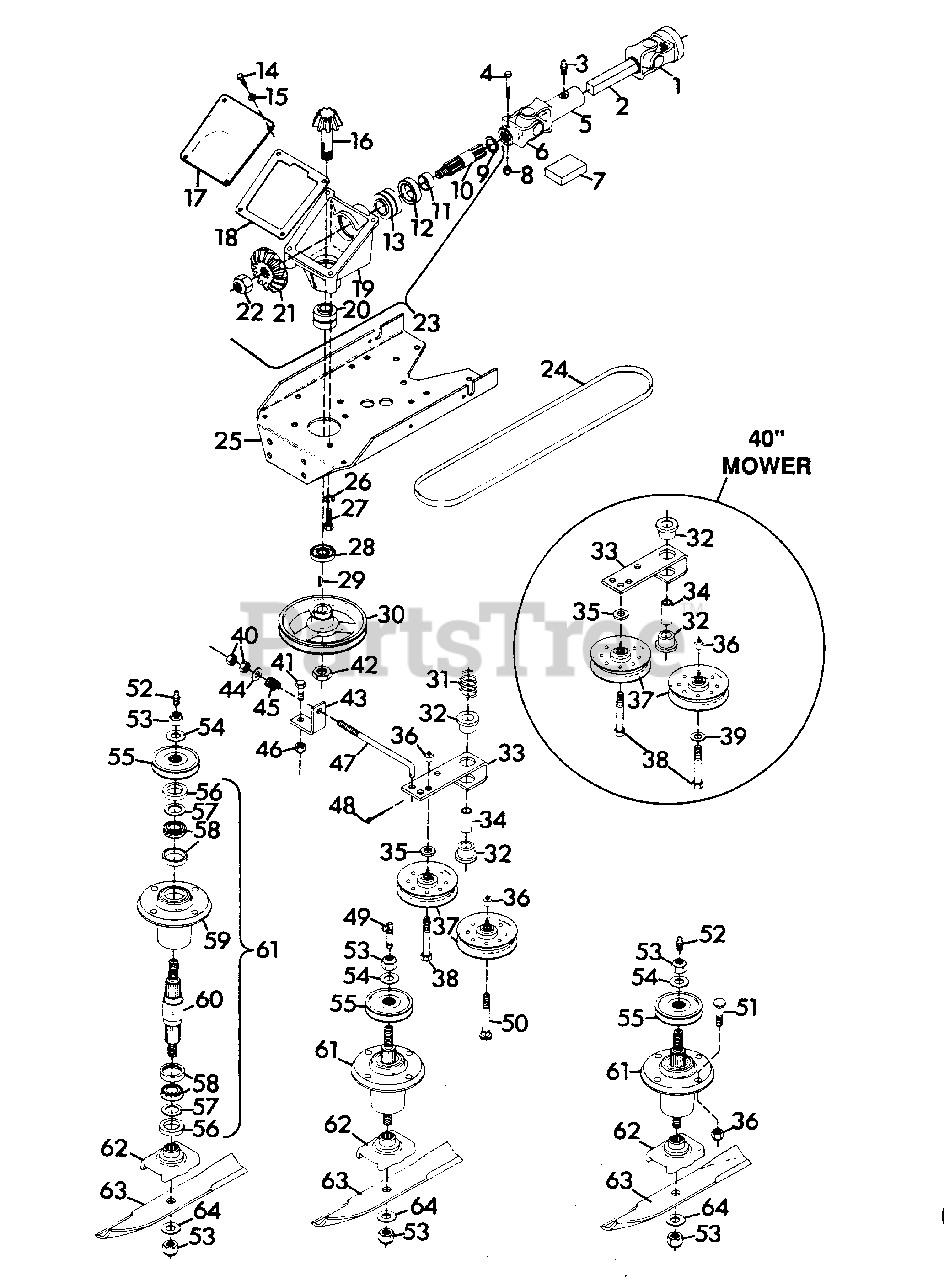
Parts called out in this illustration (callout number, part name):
1	Yoke
2	Shaft, Prop. Sq. Bar
3	Fitting, Lube 1/4-28
4	Bolt, Hex 1/4-20x2
5	U-Joint, Female End
6	Yoke(Neapco)
6	Yoke(Roscommon)
7	Kit, Repair U-Joint(Rock. Std.)
7	Kit, Repair U-Joint(Neapco)
8	Nut, Lock 1/4-20
9	Ring, Retaining 1.000 Shaft
10	Shaft, Drive
11	Spacer
12	Seal, Oil 1.250x1.987x.250
13	Assembly, Bearing 1.000x1.980x1.243
14	Bolt, Hex 1/4-20x.50
15	Washer, Lock 1/4 Reg.
16	Shaft, Pinion Gear
17	Cover, Gear Housing
18	Gasket, Gear Housing
19	Casting, Gear Box
20	Assembly, Bearing .750x1.781x1.499
21	Gear, Bevel
22	Nut, Lock 3/4-10
23	Assembly, Drive
24	Belt, 40" Mower
24	Belt, V .500x.312x126.3
25	Support, Gear Housing
26	Washer, Lock 1/2 Reg.
27	Bolt, Hex 1/2-13x1
28	Seal, Oil 1.250x1.686x.313
29	Key, Woodruff .188x.625 Hard #61
30	Sheave, 1/2x6.50
31	Spring, Comp.
32	Bushing, Nylon .760x1.000x.600
33	Arm, Idler Pivot
34	Spacer
35	Spacer, Idler .406x.750x.188
36	Nut, Lock 3/8-16
37	Sheave, Idler
38	Bolt, Hex 3/8-16x2.00
39	Washer, Flat .438x1.000x.083
40	Nut, Hex 3/8-24
41	Bolt, Hex 1/2-13x1.50
41	Bolt, Hex 1/2-13x1.375
42	Nut, Jam 3/4-10 Hex Heavy
43	Support, Spring
44	Washer, Flat .406x.812x.065
45	Spring, Comp. 1x.78x338 Lb/In
46	Nut, Lock 1/2-13
47	Rod, Idler 50" Mower
47	Rod, Idler 40" Mower
48	Pin, Cotter 3/32x1.00
49	Fitting, Lube .125 Ext. 90 Deg.
50	Bolt, 3/8-16x1.75 Rd Hd Sq Nk
51	Bolt, 3/8-16x1.25 Rd Hd Sq Nk
52	Fitting, Lube 1/8
53	Nut, Lock 5/8-11
54	Washer, Flat .687x1.312x.122/.146
55	Sheave, Spindle 40" Mower
55	Sheave, Spindle 50" Mower
56	Seal, Steel
57	Washer, Flat .975x1.970x.030
58	Assembly, Bearing
59	Housing, Bearing
60	Shaft, Spindle
61	Assembly, Spindle
62	Weldment, Blade Cradle
63	Blade, 50" Mower(Standard)
63	Blade, 50" Double Edge(Optional)
63	Blade, 40" Mower
64	Washer, Flat .656x1.312x.095
